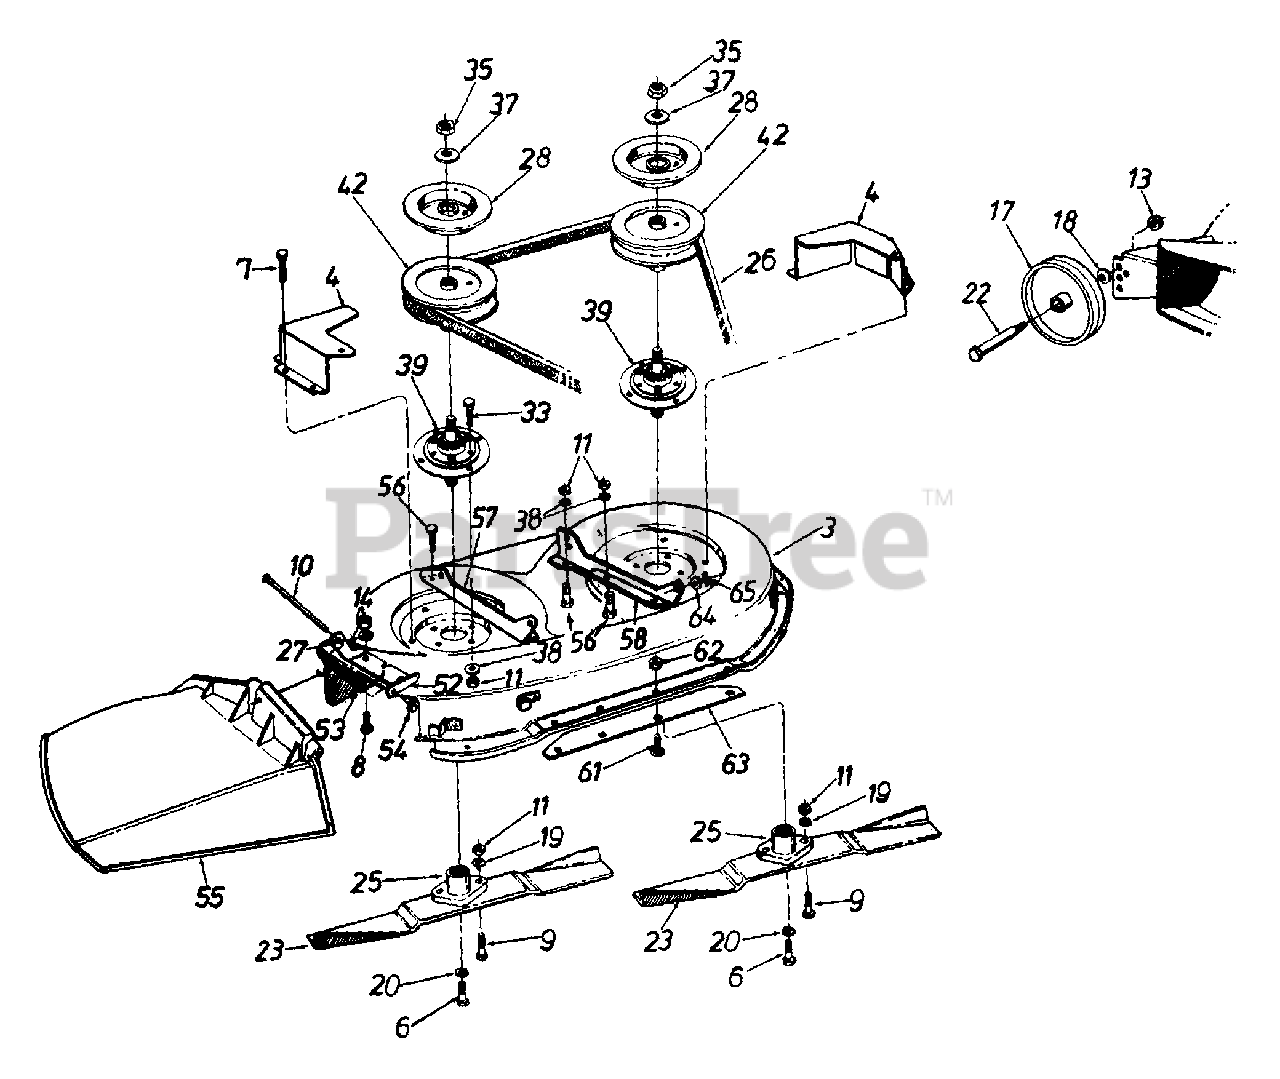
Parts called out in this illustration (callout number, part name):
6	Hex Bolt 3/8-24 x 1.0" Lg.
7	Hex Wash. Hd. TT-Tap Scr. 1/4-20 Thd.
8	Hex Bolt 1/4-20 x .62"
9	Hex Bolt Special 5/16-24 x 1.0"
10	Hinge Pin
11	Hex Nut 5/16-24 Thd.
13	Hex Top L-Nut 3/8-16 Thd.
14	Hex Nut 1/4-20 Thd.
17	Deck Wheel - 5"
18	Bell-Wash. .40" I.D. x .88" O.D.
19	L-Wash. 5/16" I.D.
20	L-Wash. 3/8" I.D.- H.D.
22	Shld. Bolt .498" Dia. x 1.53"
23	High-Lift Blade
25	Blade Adapter
26	Y-Belt
27	Bell-Wash. 1/4" I.D.
28	Brake Disc
33	Hex Bolt 5/16-24 x .75" Lg.
35	Hex Jam Nut 5/8-18 Thd.
37	L-Wash. 5/8" I.D."
38	Bell-Wash. .345" I.D. x .88" O.D.
39	Blade Spindle Ass'y. Comp.
42	5" Dia. Pulley
52	Hinge Mtg. Brkt.
53	Torsion Spring
55	Chute Ass'y. Comp.
56	Hex Bolt 5/16-24 x .75" Lg.
62	Hex Sems Nut 1/4-20 Thd.
65	Hairpin Clip 3/8" Dia.
